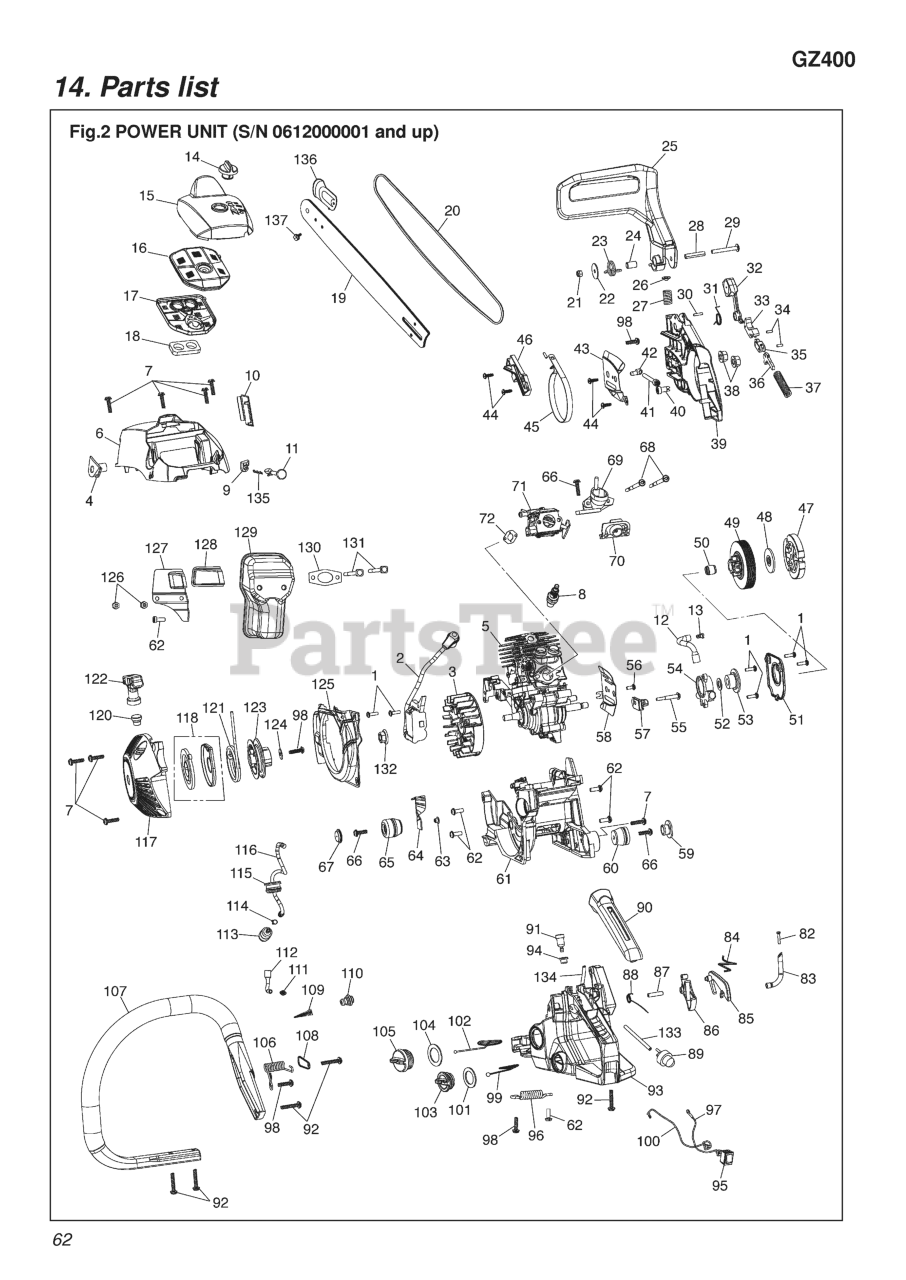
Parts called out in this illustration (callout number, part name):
2	COIL ASSY
3	ROTOR COMP
5	ENGINE ASSY
6	CYLINDER COVER
7	SCREW
8	SPARK PLUG
9	GROMMET
11	CHOKE ROD
12	PIPE
13	PIN FOR PIPE OUT COMP
14	KNOB, COVER
15	CLEANER COVER
16	UPPER CLEANER/NAT
17	LOWER CLEANER/NAT
18	SEAL FOR CLEANER ASSY
19	BAR 18
20	CHAIN, 18
21	NUT
23	SPRING, RETURN
25	FRONT GUARD
26	STOPPER PLATE
27	SPRING, STOPPER
28	SPACER FOR GUARD
31	SPRING, STOPPER
32	WEIGHT, ARM
33	LEVER, BRAKE
36	ARM, SLIDE
37	SPRING, BRAKE
38	NUT
39	CHAIN COVER
40	GEAR
41	SCREW
42	NUT, ADJUST
43	PLATE FOR GUIDE
45	BAND, BRAKE
46	SPRING COVER
47	CLUTCH ASSY
49	DRUM
50	BEARING FOR CLUTCH DRUM
51	OIL PUMP COVER, BLACK
52	WASHER, PUMP WORM
53	WORM, OIL PUMP ASSY
54	OIL PUMP BODY ASSY
57	CATCHER, CHAIN-BLK
58	CHAIN GUIDE PLATE
59	CAP (T), DAMPER-BLK
60	DAMPER
61	CASE ENGINE
62	SCREW
63	EYELET
64	STOPPER
65	DAMPER COMP
66	SCREW
67	CAP, DAMPER-BLK
69	INTAKE MANIFOLD
70	GROMMET, THROTTLE ROD
71	CARBURETOR ASSY
72	CARB GASKET
83	PIPE, BREATHER
84	ROD, THROTTLE
85	ARM SAFETY ROCK
86	LEVER, THROTTLE
87	SPRING PIN
88	SPRING, THROTTLE
89	PRIMER ASSY
90	COVER, GRIP
91	BREATHER ASSY
93	HANDLE COMP
95	STOP SWITCH ASSY
96	SPRING F, DAMPER
98	SCREW
99	STOPPER FOR CAP ASSY
100	CORD/RED
101	GASKET
103	CAP BODY, CAP ASSY
104	GASKET, TANK CAP
105	CAP TANK CAP
106	SPRING R, DAMPER
107	L HANDLE
108	DAMPER PLATE
109	CONE SPRING
110	GROMMET, OIL FILTER
111	JOINT, PIPE IN COMP
112	OIL PIPE, IN
113	FUEL FILTER
114	CLIP FUEL PIPE
115	GROMMET PIPE
116	RUBBER TUBING
117	RECOIL CASE
118	SPRING COMP
120	GUIDE, RECOIL STARTER
121	ROPE
122	KNOB
123	REEL
124	WASHER
125	COVER, FAN
126	MUFFLER NUT
127	STAY
128	ARRESTER
129	MUFFLER ASSY
130	MUFFLER GASKET
131	BOLT
132	NUT
133	RUBBER TUBING
134	RUBBER TUBING
135	PIN HAIR
136	SAFETY TIP
NI	CHAIN, 18
